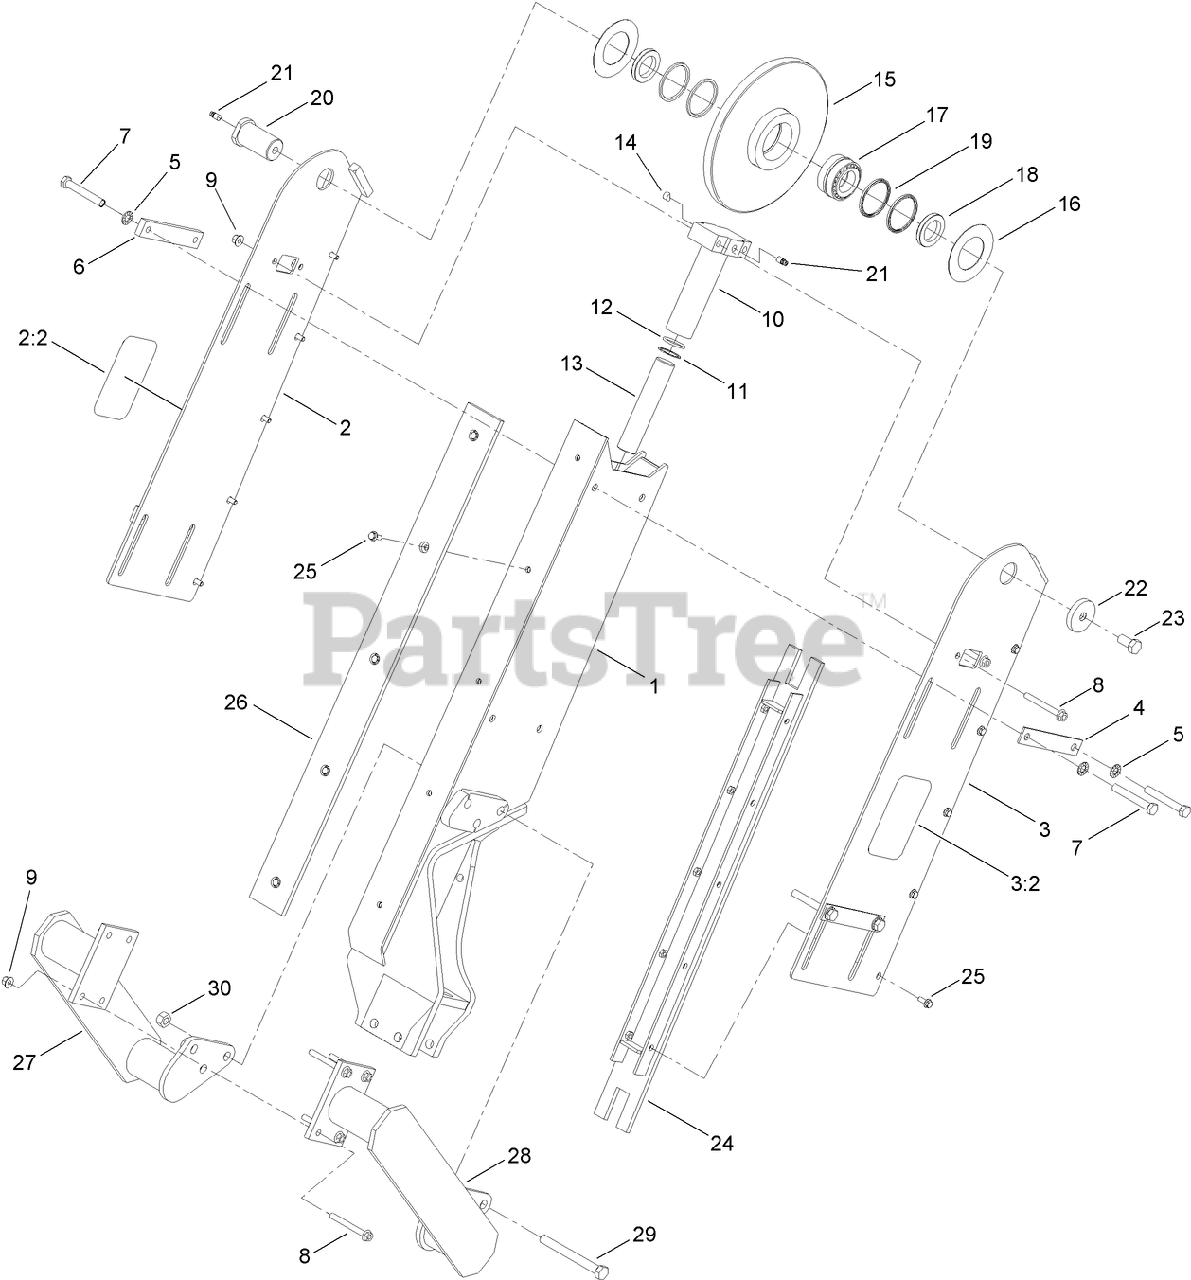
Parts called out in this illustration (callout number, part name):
1	BOOM-48IN ROCK
2	RH BOOM END PLATE ASM
3	LH BOOM END PLATE ASM
4	BAR-CLAMP
5	WASHER-LOCK
6	BAR-TAPPED
8	BOLT-HHF
9	NUT-LOCK, HHF
10	BOOM END CYLINDER ASM
11	WASHER-BACKUP
13	ROD-BOOM, END (CYLINDER)
14	PLUG-BLEED
15	ROLLER-BOOM END
16	WASHER-BOOM, END (ROLLER)
17	BEARING KIT
18	SPACER-bearing
19	SEAL-ROLLER
20	PIN-BOOM
21	FITTING-LUBE, STRAIGHT
24	CHANNEL-WEAR PAD, 4IN
25	SCREW-HHF
26	BAR-WEAR, PAD
27	MOUNT-CRUMBER, RH (ROCK)
28	MOUNT-CRUMBER, LH (ROCK)
30	NUT-LOCK
